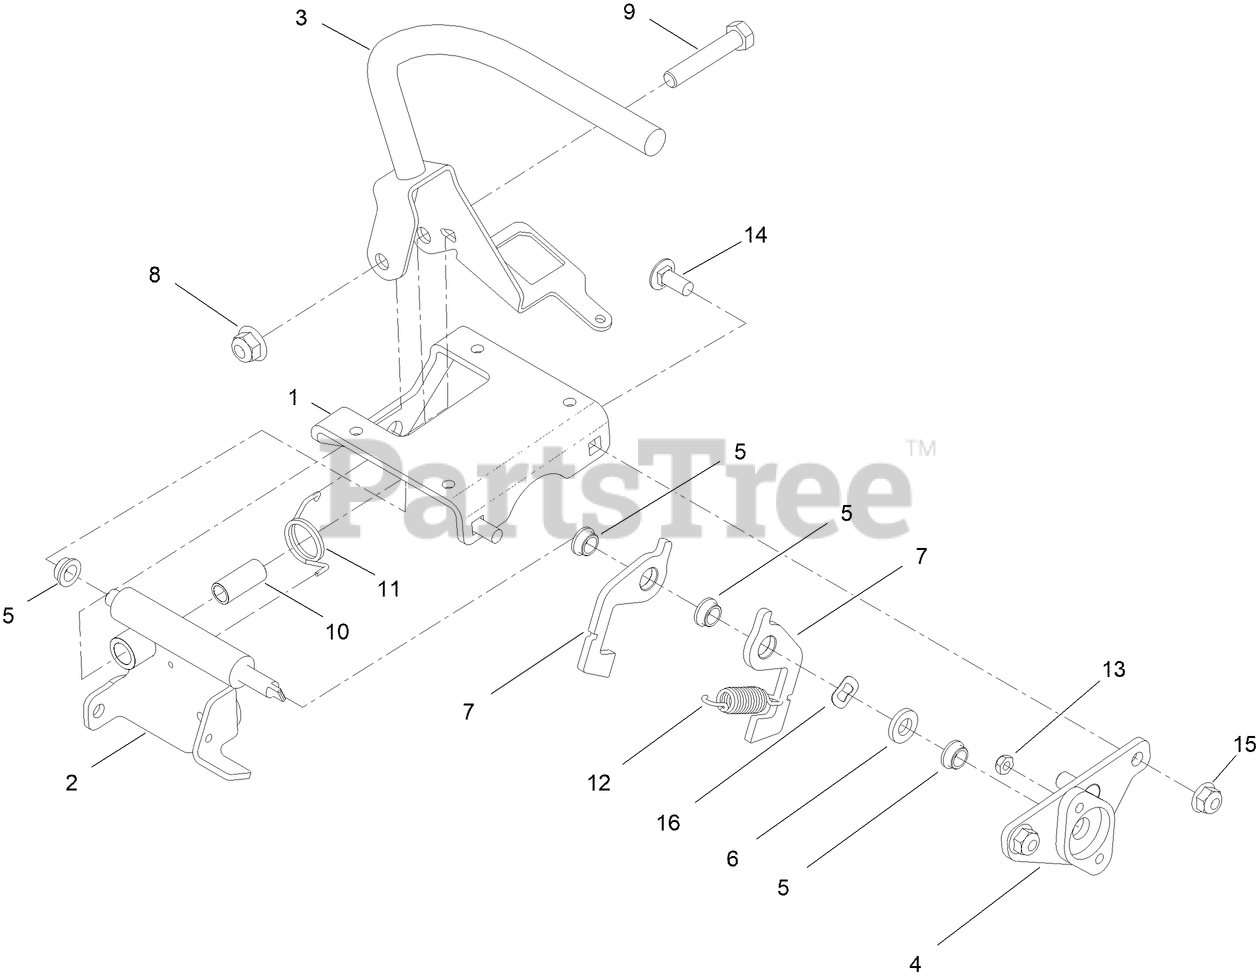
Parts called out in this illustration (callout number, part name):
1	BRACKET-CONTROL MOUNT
2	MOTION CONTROL ASM RH
3	RH LEVER ASM
4	PLATE ASM-SENSOR RH
5	BUSHING-FLANGED NYLON
6	WASHER
7	PLATE-SPRING
8	NUT-HF, NI
9	SCREW-HH
10	BEARING-SLEEVE
11	SPRING-TORSION
12	SPRING-EXTENSION
13	NUT-LOCK, NI
14	SCREW-CARR
15	NUT-HF, NI
16	WASHER-WAVE
